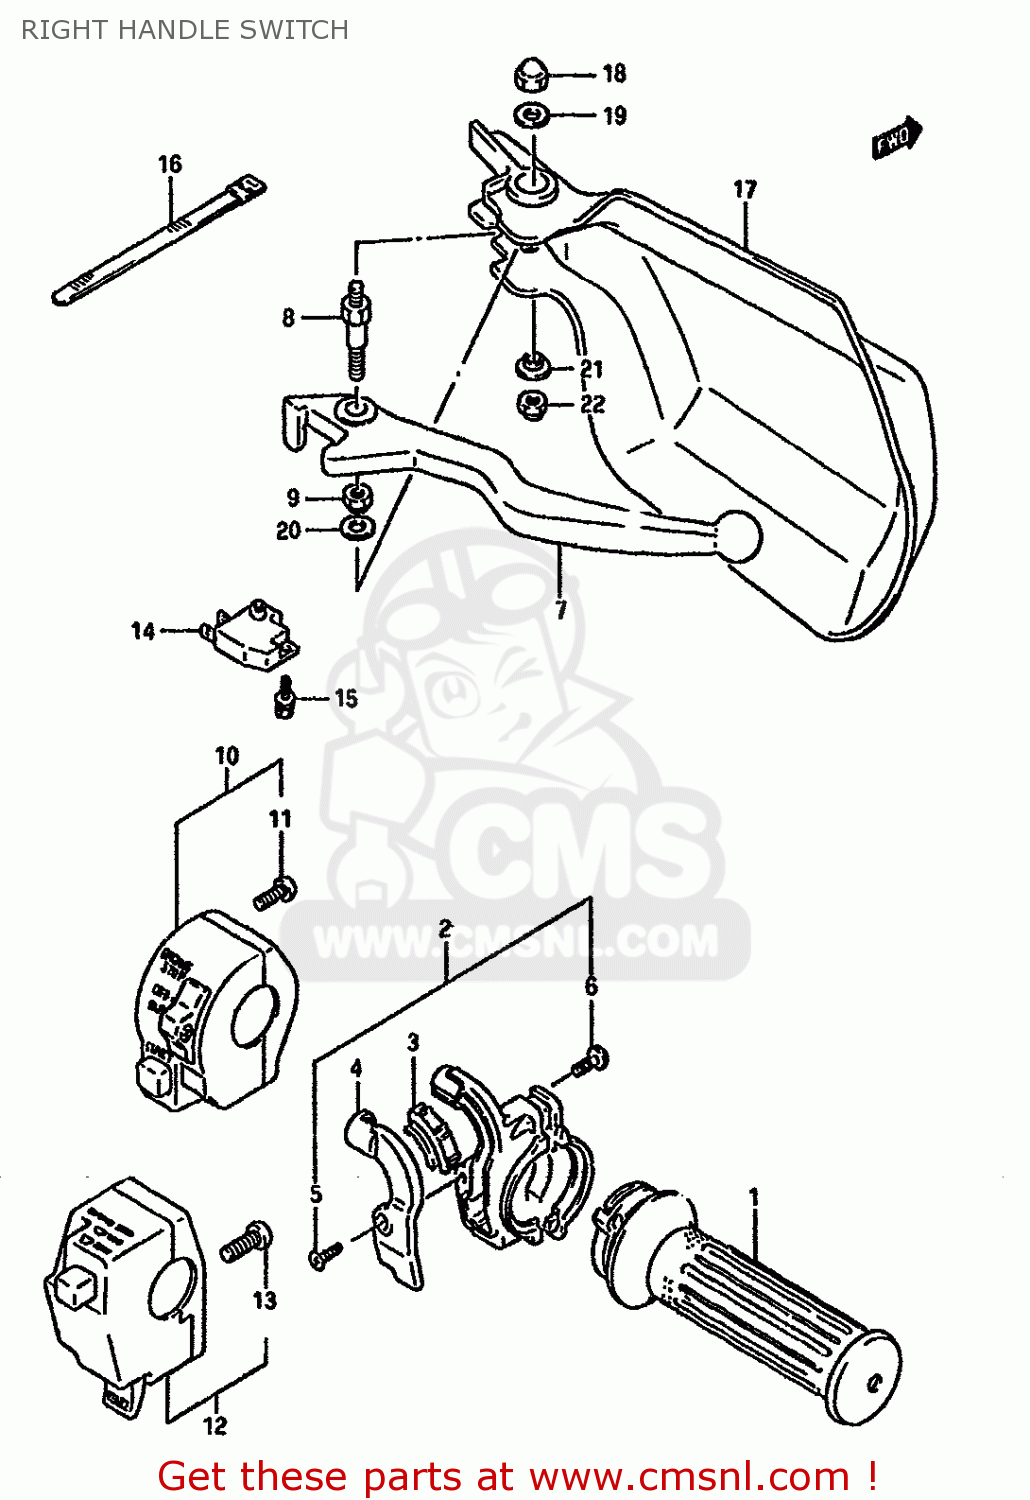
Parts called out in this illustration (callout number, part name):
1	GRIP ASSY,THROTTLE
2	CASE ASSEMBLY,THROTTLE
3	GUIDE PIECE,THROTTLE
4	COVER,THROTTLE CASE
5	SCREW 4X10
6	SCREW
7	LEVER,BRAKE
8	BOLT,BRAKE LEVER PIVOT
9	NUT
10	SWITCH ASSY,HANDLE RH
11	SCREW
12	SWITCH ASSY,HANDLE RH
13	SCREW
14	SWITCH ASSEMBLY,STOP
15	SCREW
16	CLAMP(L:120)
17	GUARD,KNUCKLE RH (BLUE)
18	NUT 6MM
19	WASHER (6.5X20X1.6)
20	WASHER(6.5X16X1.2)
21	WASHER
22	NUT
